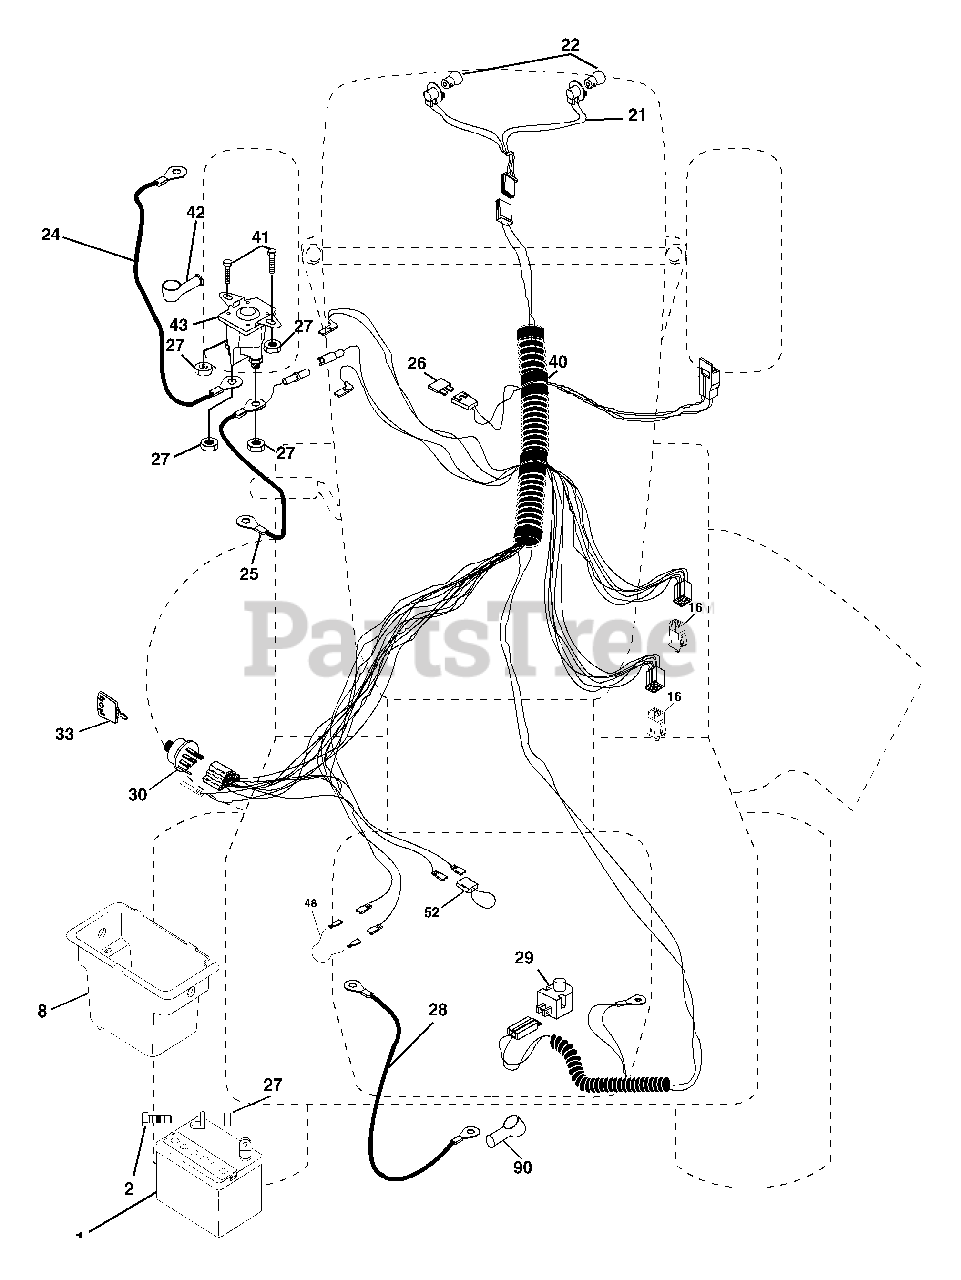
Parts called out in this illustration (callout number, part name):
1	Battery
2	Bolt Hex Hd 1/4-20 unc x 3/4
8	Box Battery
16	Switch Interlock
21	Harness Asm Light W/4152j
22	Bulb Light #1156
24	Cable Battery 6 Ga. 11"red
25	Cable Battery
26	Fuse 20 AMP
27	Nut Keps Hex 1/4-20 unc
28	Cable Ground 6 Ga. 12"black
29	Switch Plunger Nc Gray
30	Switch Ign
33	Key Ign
40	Harness Ign
41	Bolt Blk Fin Hex 1/4-20
42	Cover Terminal Red
43	Solenoid
48	Adapter Ammeter
52	Protection Wire Loop
90	Cover Terminal Battery
